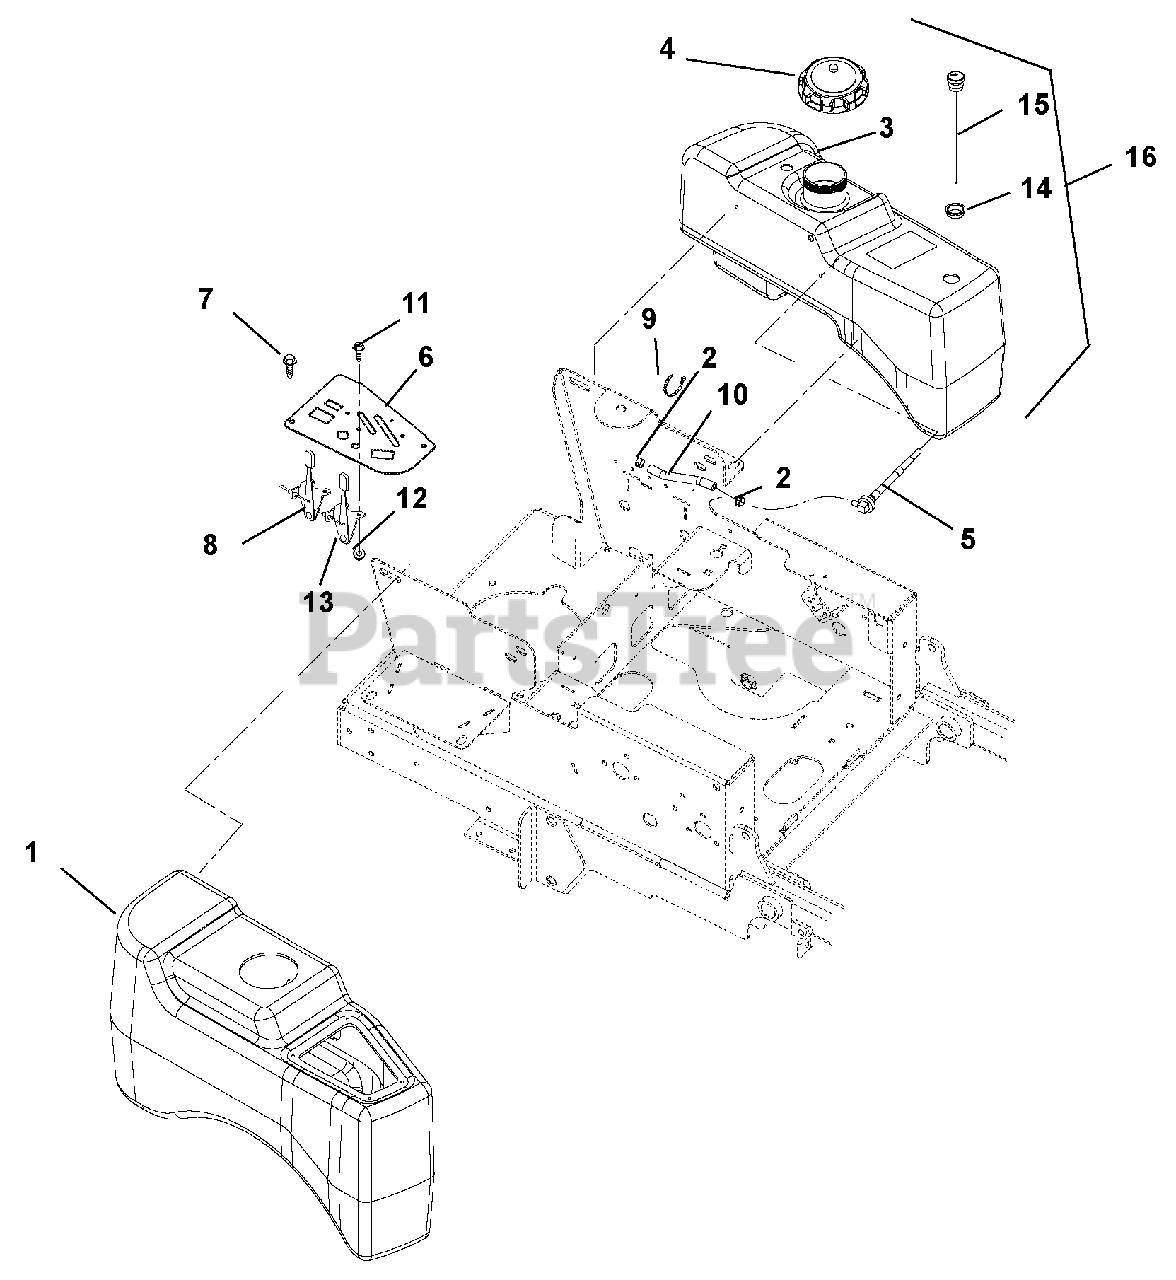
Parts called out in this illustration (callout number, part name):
1	Fender Right Hand
2	Clamp, Fuel Line
3	Tank, Fuel Left Hand
4	Cap, Fuel Ratcheting
5	Assembly, Tank Fuel Pick-up
6	Panel, Control
7	Screw, Plastite .25 x 10 x .75 YZ
8	Cable, Control (991082, 083, 084, 090)
8	Cable, Control (991091)
9	Cable Tie
10	Hose, .25 Low-PERM Bulk Gas
11	Screw, Machine 10-24 x .50 Hex Washer Head
12	Nut, Locking Nylon 10-24 with Insert
13	Cable, Throttle Control (991090)
14	Grommet, Fuel Gauge
15	Gauge, Remote Fuel 10.0"
16	Fuel Tank Assembly (Includes item 3, 4, 5, 14, 15; page 11 Item 1 , 2)
